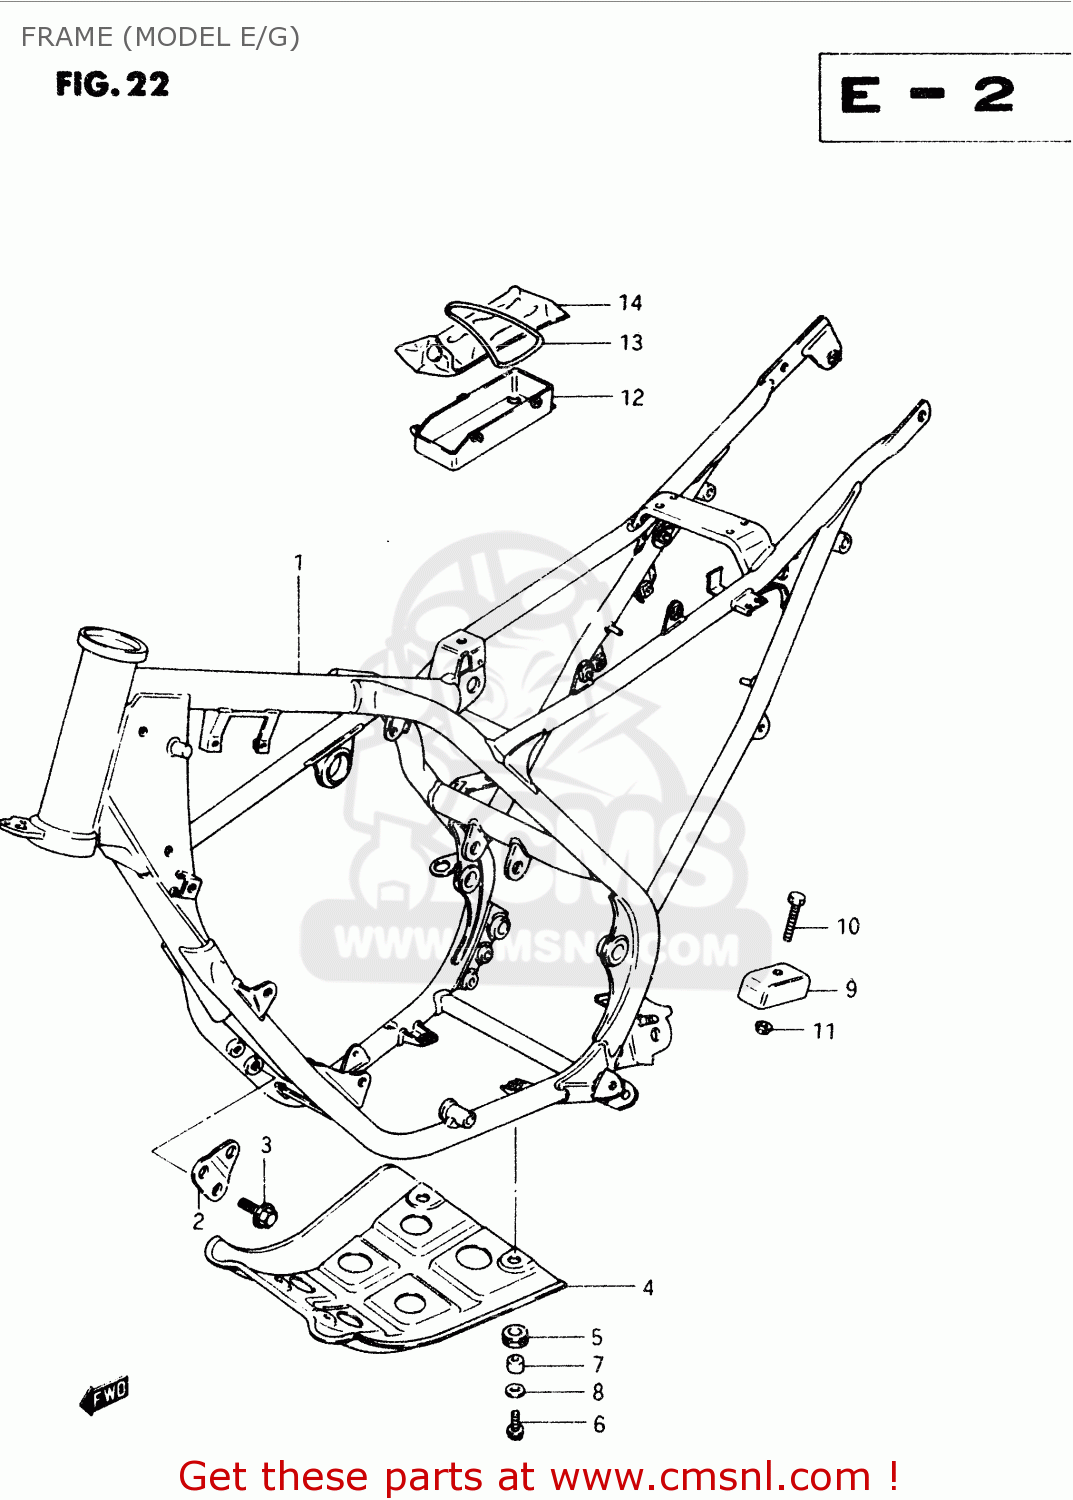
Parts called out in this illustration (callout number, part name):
1	FRAME (BLUE)
2	PLATE,ENG MTG
3	BOLT, LOWER
4	PROTECTOR, ENGINE
5	CUSHION
6	BOLT
7	SPACER (6X9X5)
8	WASHER(6.5X18X1)
9	GUIDE,CHAIN CONTROL
10	BOLT
11	NUT
12	HOLDER, TOOL
13	O RING(D:3.53,ID:69.44)
14	TOOL ASSY
